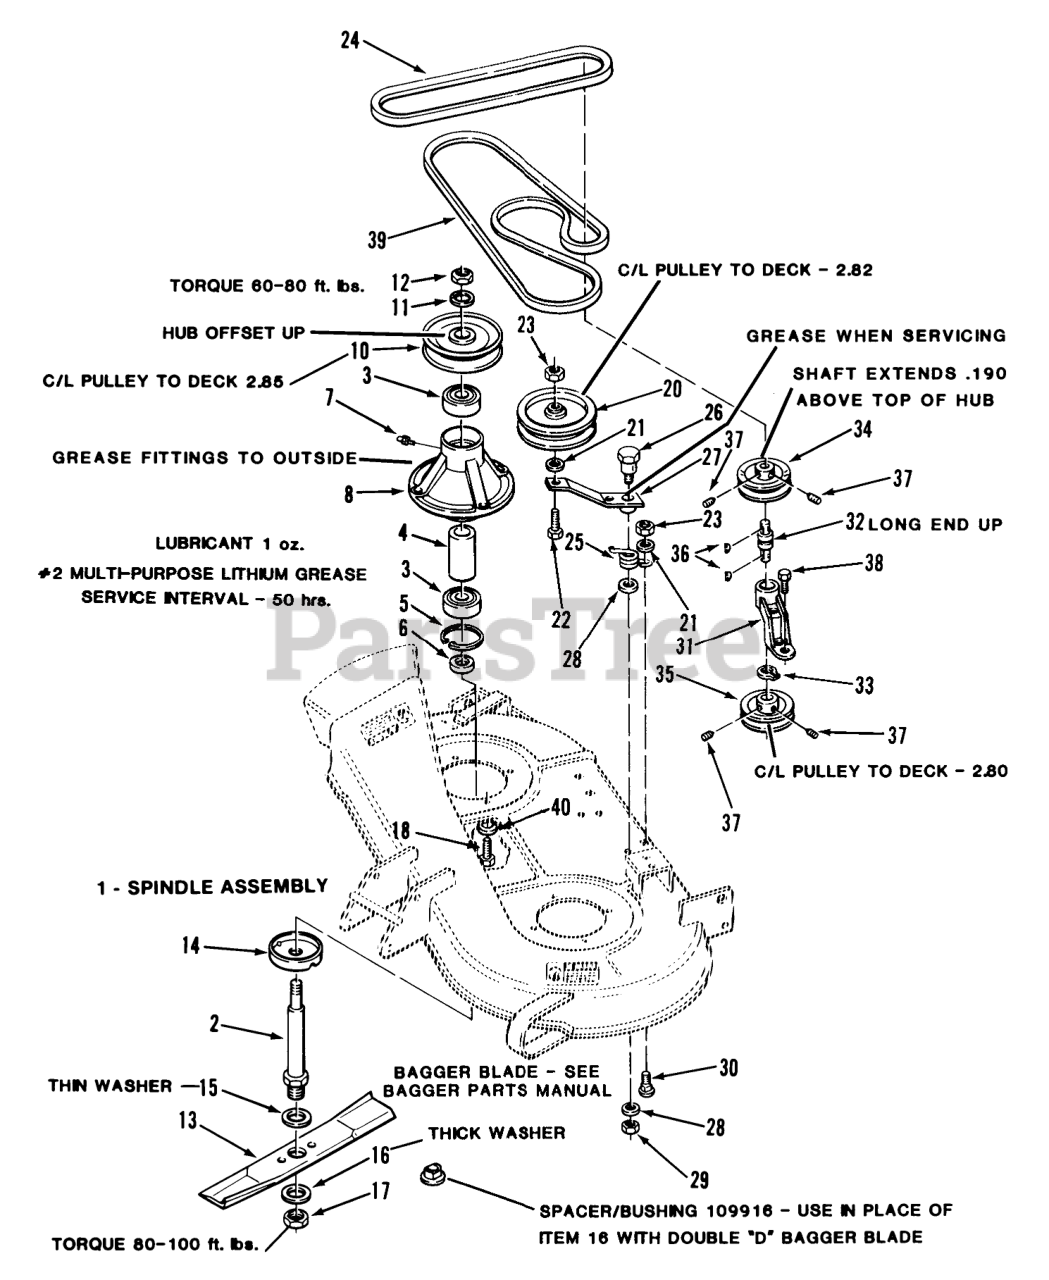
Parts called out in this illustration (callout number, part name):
1	Spindle Assembly (Includes Items 2 to 8, 14)
2	SHAFT SPINDLE
3	BEARING-BALL
5	Ring-Snap
6	SPACER-BLADE
7	Fitting-Grease
8	HOUSING SPINDLE
10	PULLEY BLADE
11	Lockwasher
12	Jam Nut
13	ASSY BLADE KIT
14	CUP-SPINDLE
15	Washer
16	SpeciaI Washer
17	Nut-Jam
18	BOLT
20	Idler Pulley
21	Washer
22	Bolt
23	Nut
24	V-BELT
25	SPRING-TORSION
26	BOLT-SHOULDER
27	Idler Arm
28	WASHER
29	NUT-JAM(7/16-14)
30	Bolt
31	HOUSING DRIVE BRG R
32	BEARING-INT SHAFT
33	Snap Ring
34	PULLEY
35	PULLEY-SPLIT
36	KEY-WOODRUFF
37	Set Screw
38	Bolt
39	BELT-V MOWER
40	LOCKWASHER
